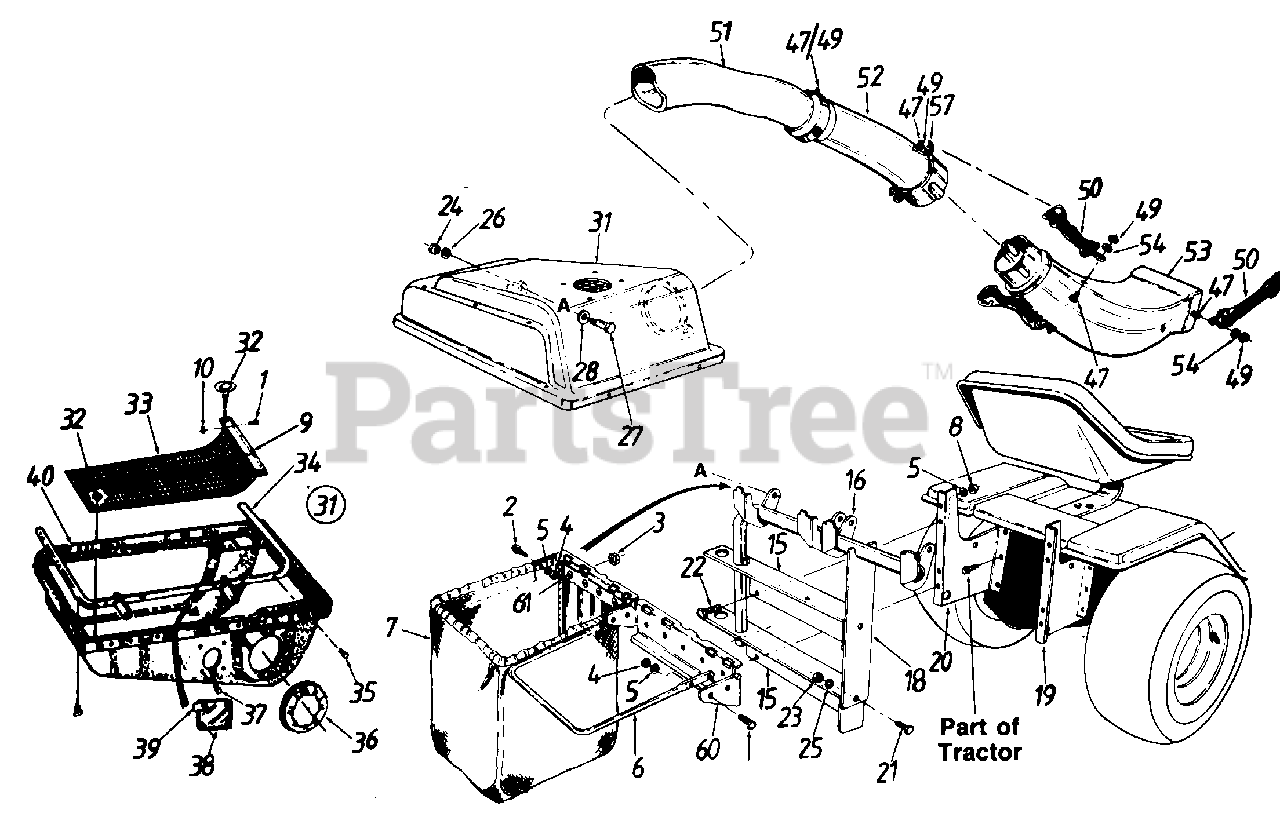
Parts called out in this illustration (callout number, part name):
1	Pop Rivet .188 Dia.
2	Hex Bolt 1/4-28 x .'5"
3	Hex Sems Nut #10-24 Thd.
4	Hex Nut 1/4-28 Thd.
5	L-Wash. 1/4" I.D.
7	Grass Catcher Bag
8	Hex Nut 1/4-20 Thd.
9	Screen Mtg. Brkt.
10	Flat Wash. 1/4" I.D.
15	Catcher Support Tube Mtg. Brkt.
16	Catcher Support Tube Ass'y.
18	Catcher Latch and Support Brkt.
19	Grass Catcher Support Brkt. R.H.
20	Grass Catcher Support Brkt. L.H.
21	Hex Bolt 5/16-18 x .75"
22	Hex Bolt 1/4-20 x .62" Lg. Grade 5
23	Hex Nut 5/16-18 Thd.
24	Hex Nut 3/8-16 Thd.
25	L-Wash. 5/16" I.D.
26	L-Wash. 8/8" I.D.
27	Shld. Bolt 3/8-16 x .50" Dia.
28	Bell-Wash. .505" I.D. x 1.0" O.D.
31	Grass Catcher Cover Ass'y.
32	Twist Fastener
33	Screen
35	Hex AB-Tap Scr. 1/4 x .62"
37	Truss Mach. B-Tap Scr. #10 x .5" Lg.
38	N Plastic Plate
39	Speed Nut
40	N Grass Catcher Cover
47	Hex Bolt 1/4-20 x .5"
49	Hex Ins. L-Nut 1/4-20 Thd.
50	Retainer Strap Ass'y.
51	Catcher Elbow
52	Catcher Tube
53	Discharge Chute
54	L-Wash. .27" I.D.
57	Retainer Hook Brkt.
61	Truss Mach. Scr. #10-24 x .5" Lg.
